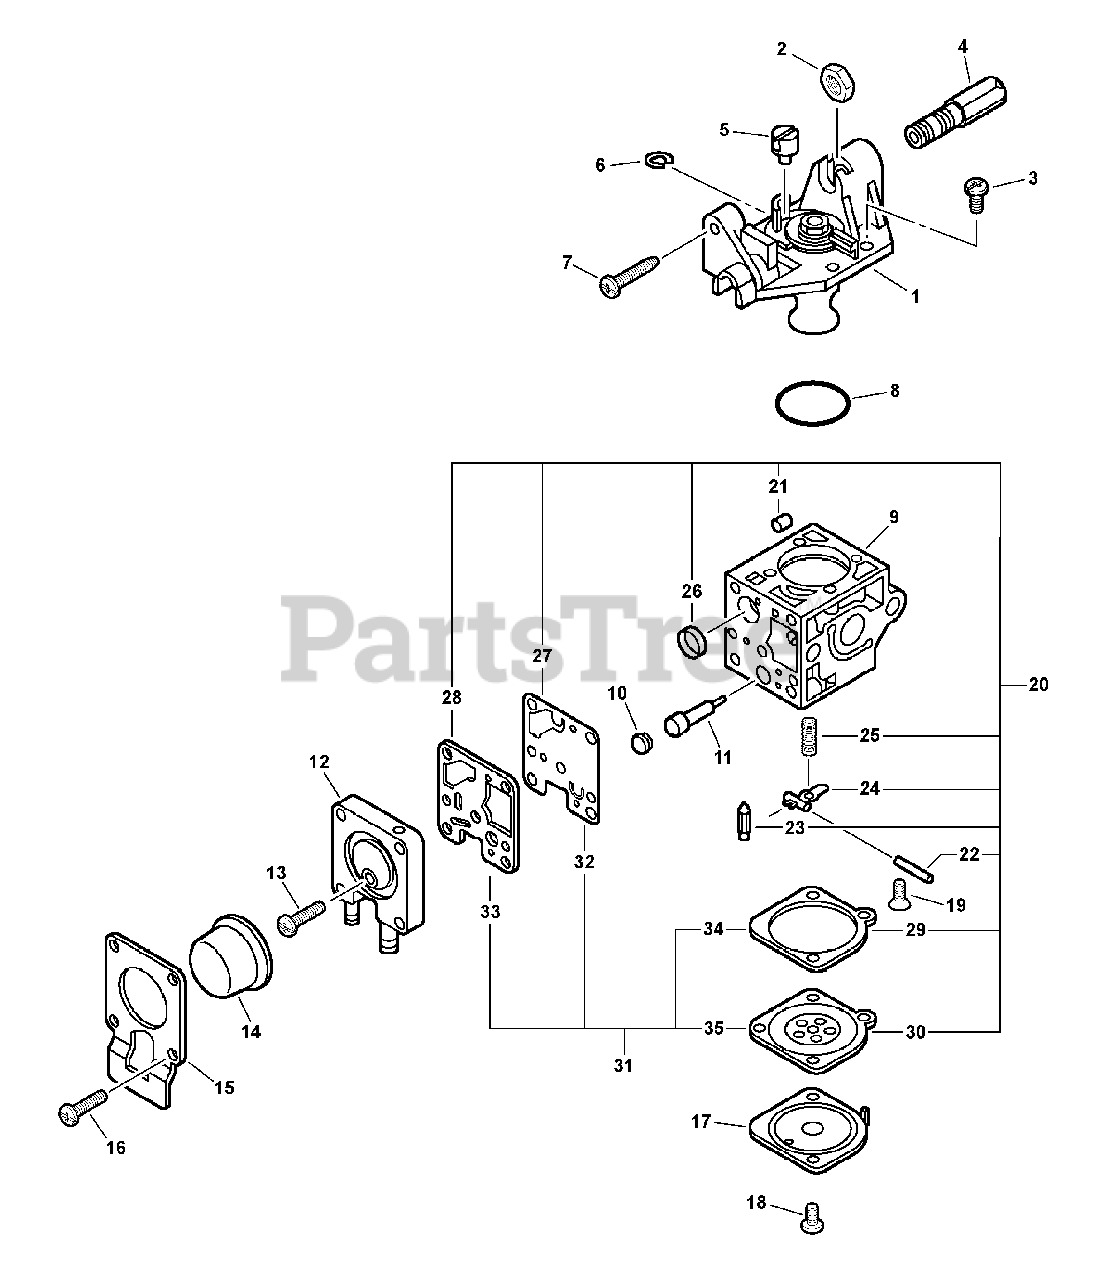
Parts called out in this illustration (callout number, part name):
1	Rotor Cover Asy
2	Nut, Cable
3	Screw, Rotor Cover Asy
4	Screw, Cable Adjust
5	Swivel
7	Screw, Throttle Adjust
9	Body, Carburetor
11	Needle - High Speed
12	Purge Base Asy
13	Screw, Purge Base Asy
14	Bulb, Purge
15	Retainer, Purge Bulb
16	Screw, Purge Bulb Retainer
17	Cover, Diaphragm
18	Screw, Diaphragm Cover
19	Screw, Metering Lever Pin
20	Repair Kit
21	Roller, Guide
22	Pin, Metering Lever
23	Valve, Inlet Needle
24	Lever, Metering
25	Spring
26	Strainer
27	Diaphragm, Pump
28	Gasket, Pump
29	Gasket, Metering
30	Diaphragm, Metering
31	Diaphragm/Gasket Kit
32	Diaphragm, Pump
33	Gasket, Pump
34	Gasket, Metering
35	Diaphragm, Metering
